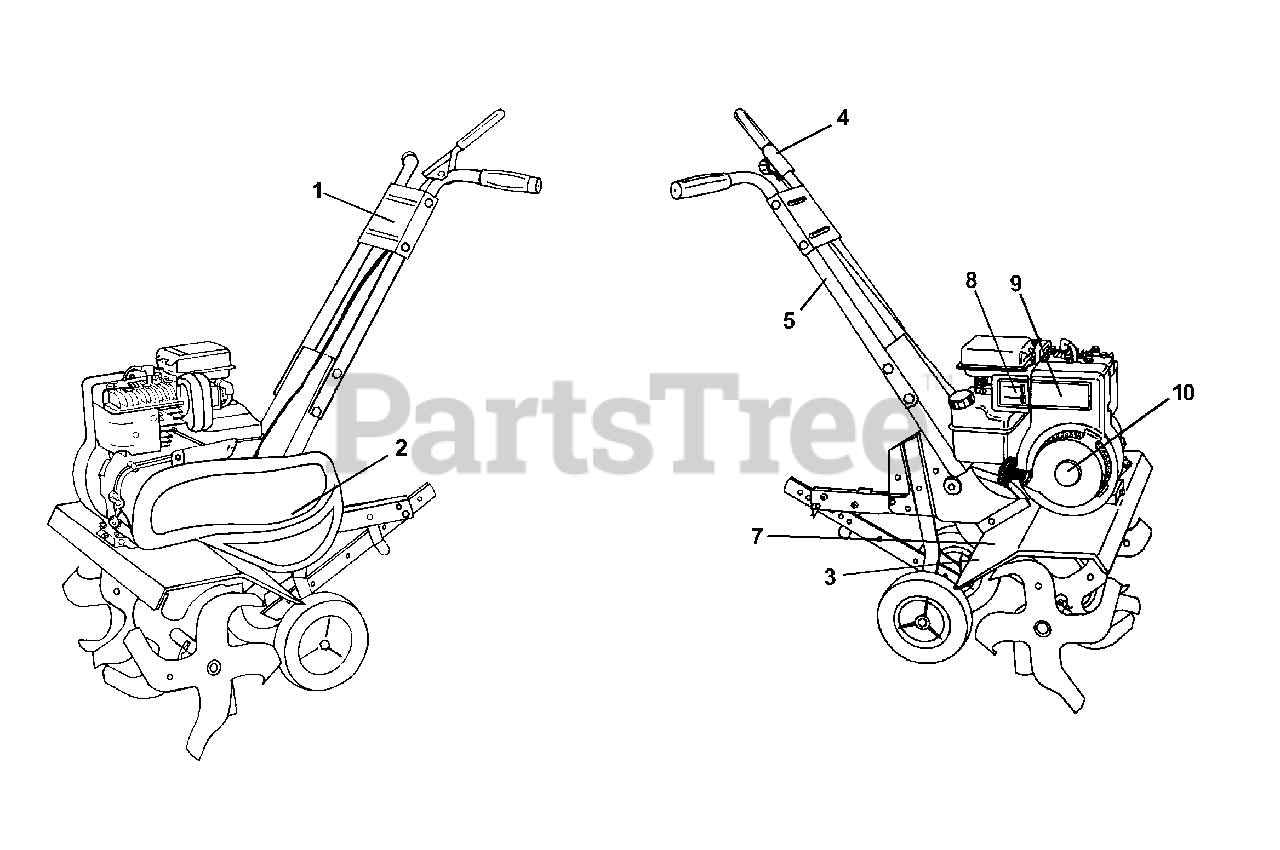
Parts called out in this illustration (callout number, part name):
1	Decal, Logo Control Panel
2	Decal, Logo Belt Guard
3	Decal, Warn. Till.
4	Decal, Tine Control
5	Decal, Hand Placement
7	Decal, Warning, Rotating Tines
8	Decal, Speed Control
9	Decal, 3.5 HP
10	Decal, Briggs & Stratton
